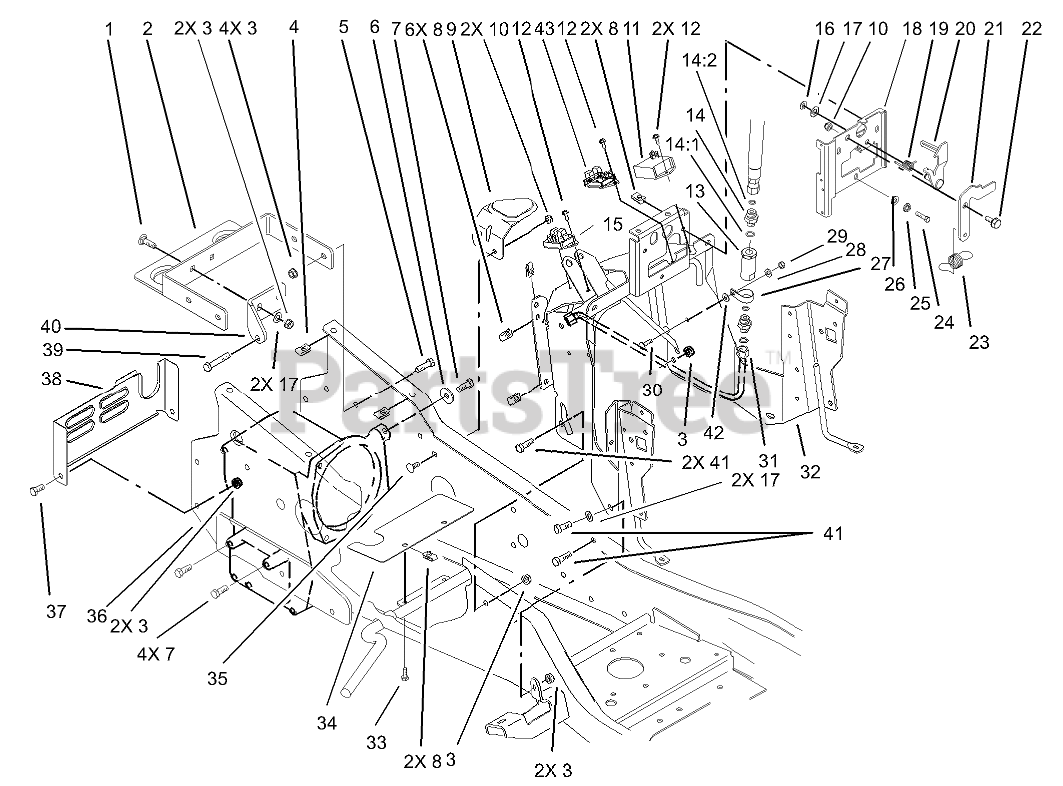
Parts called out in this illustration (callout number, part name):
1	BOLT-CARR
2	Support-Gas Tank
3	NUT-LOCK, NI
4	NUT-U
5	SCREW-HH
6	WASHER
7	SCREW-HH, LOCK
9	SUPPORT-TANK, FUEL
10	NUT-LOCK, NI
11	MODULE-LOW FUEL
12	SCREW-HWH
13	FILTER-SCREEN, HYD
14	FITTING-HYD. STRAIGHT
14:1	O-RING
14:2	O-RING
15	MODULE-CRUISE
16	RING-RETAINING
17	WASHER-FLAT
18	BRACKET-LATCH
19	SPRING-LEVER, LATCH
20	LEVER-LATCH
21	LATCH-LEVER, TENSION
22	BOLT-SHOULDER
23	SPRING-LEVER, LATCH
24	SCREW-HH
25	WASHER-LOCK
26	WASHER-FLAT
27	CLAMP-R
28	WASHER-FLAT
29	NUT-LOCK, NI
30	BOLT-CARR
31	TUBE-HYD
32	TOWER ASM
33	SCREW-HH
34	BAFFLE-FAN
35	SCREW-CARR
37	SCREW-HH
38	COVER-REAR
39	SCREW-HH W/LOCTITE
40	Strap-Torque
41	SCREW-HH
42	PUSHNUT-RETAINER, BOLT
43	MODULE-CLUTCH
